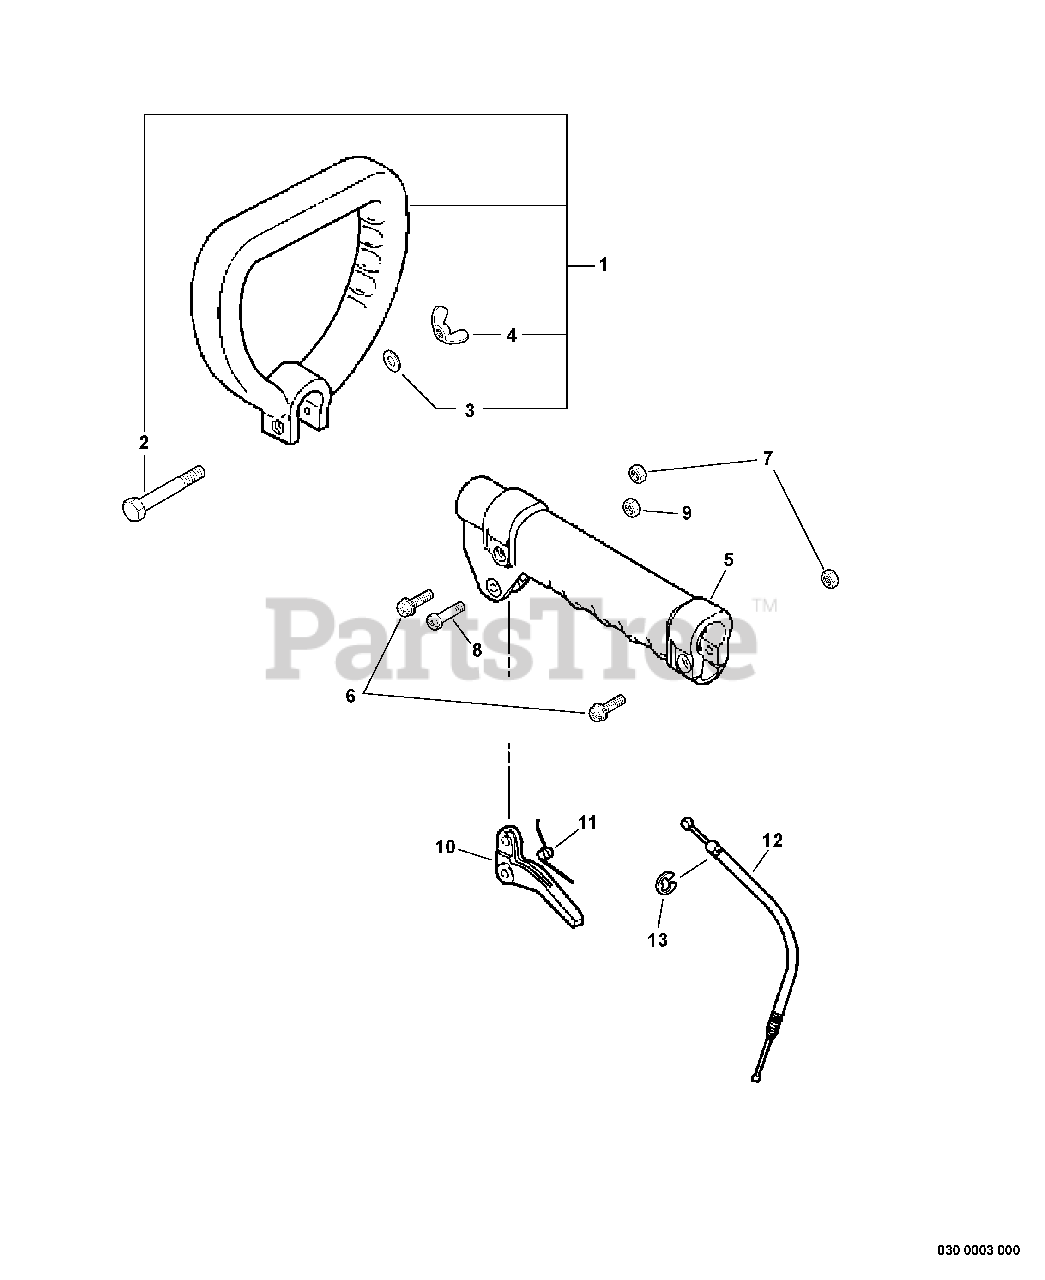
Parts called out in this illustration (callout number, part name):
1	HANDLE ASSY
2	BOLT 1/4"-20×1-1/2"
3	WASHER, 1/4"
4	NUT, WING 1/4"-20
6	SCREW 5×25
7	NUT M5
9	NUT, LOCK M5
10	TRIGGER, THROTTLE
11	SPRING, THROTTLE
12	CABLE, THROTTLE
13	RING, RETAINING - 5
